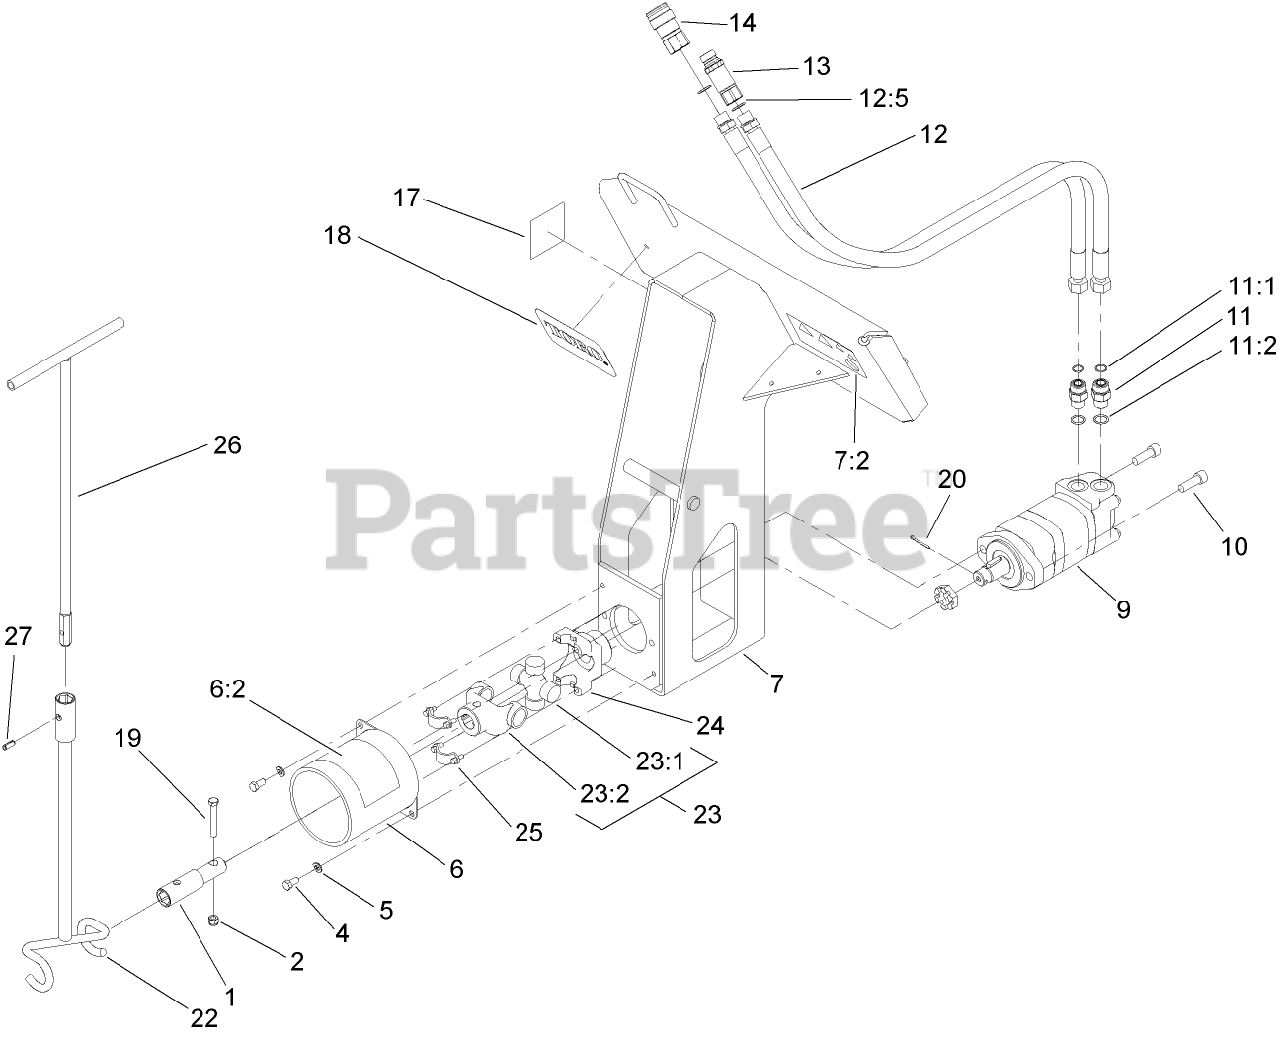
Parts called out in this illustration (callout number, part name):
1	COUPLER ASM
2	NUT-LOCK, NI
4	SCREW-HH
5	WASHER-LOCK
6	Shield ASM
6:2	DECAL-WARNING
7	Bore Frame ASM
7:2	DECAL-WARNING
9	MOTOR-HYDRAULIC
10	SCREW-HSH
11	FITTING-STRAIGHT
11:1	O-RING
11:2	O-RING
12	HOSE ASM
12:5	O-RING
13	NIPPLE-CONNECT, PRESSURE
14	COUPLER-FACE, FLUSH
17	DECAL
18	DECAL
19	SCREW-HH
20	PIN-COTTER
22	TOOL-GUIDE, ROD
23	YOKE ASM
23:1	U-JOINT
23:2	YOKE-U-JOINT
24	YOKE-U-BOLT
25	Bearing Strap Kit
26	HANDLE-TOOL, GUIDE
27	PIN-ROLL
